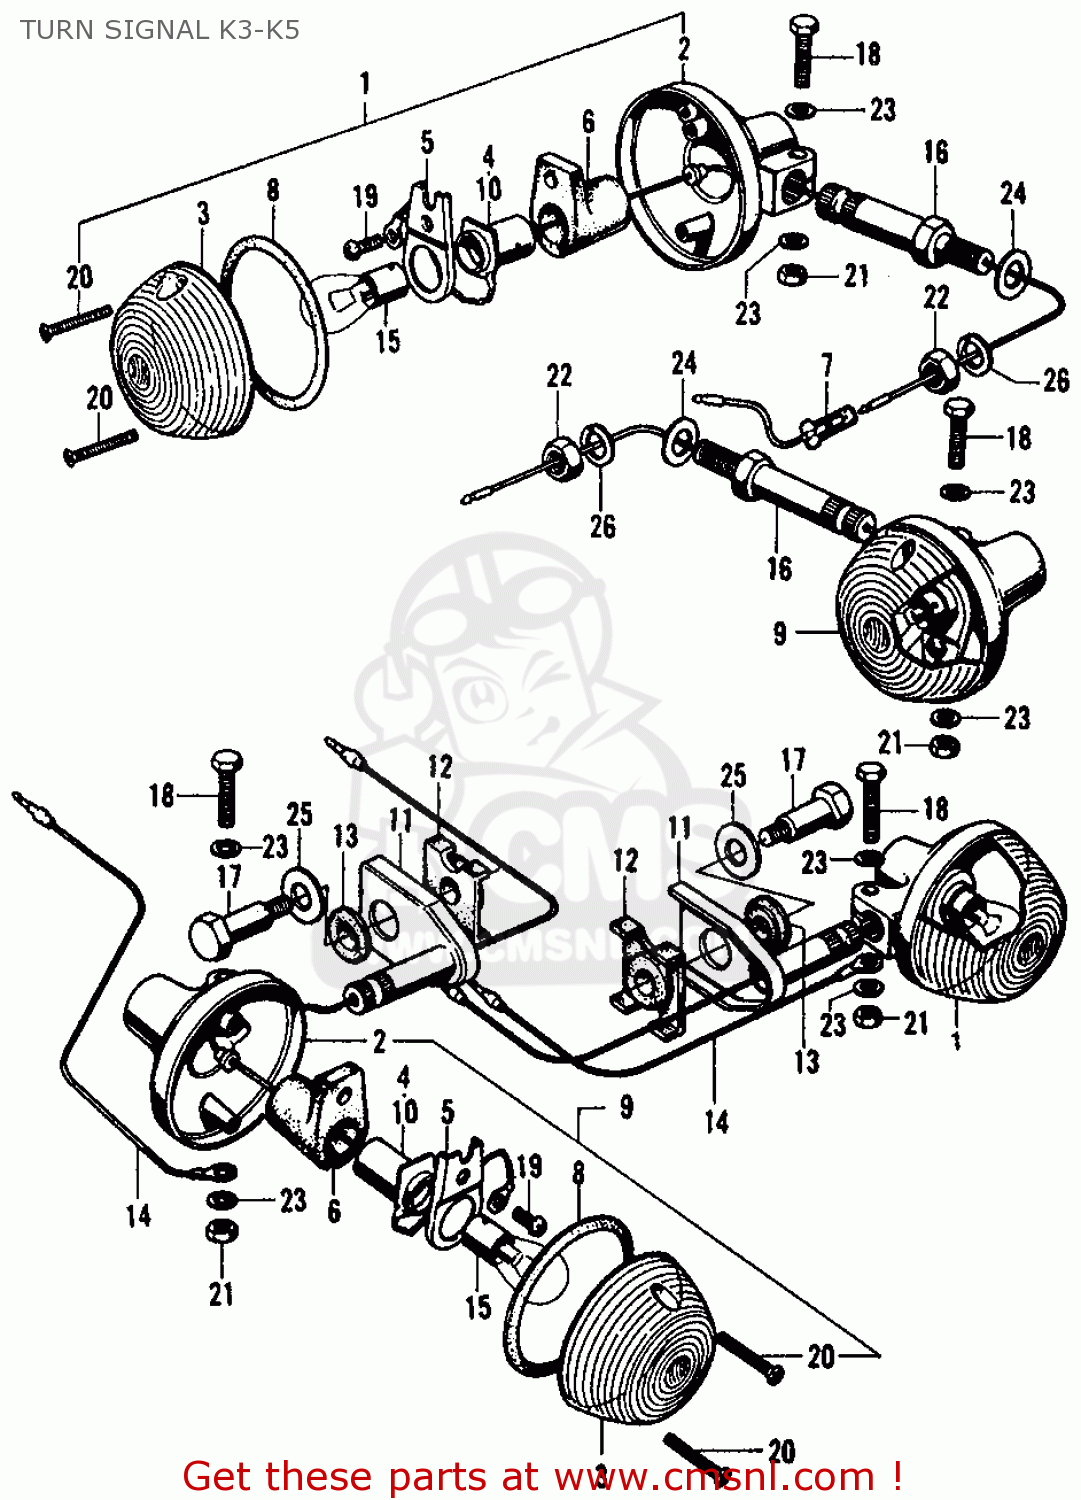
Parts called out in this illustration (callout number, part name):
1	WINKER ASSY 74IE
2	BASE,WINKER
3	LENS WINKER
4	SOCKET,R.WINKER
5	SOCKET,WINKER
6	RUBBER,WINKER
7	CORD,F.WINKER SUB
8	PACKING,LENS
9	WINKER ASSY 74IE
10	SOCKET,L.WINKER
11	STAY,REAR WINKER
12	RUBBER,MOUNT
13	RUBBER,MOUNT
14	CORD,WINKER EARTH
15	BULB, WINKER
16	BOLT, RIGHT CASE
17	BOLT,WINKER SET
18	BOLT, HEX., 6X28
19	SCREW,CROSS 5X8
20	SCREW CROSS 3X25
21	NUT HEX 6MM
22	NUT,HEX.,10M/M
23	WASHER PLAIN 6MM
24	WASHER 10MM
25	WASHER,PLAIN,12MM
26	SPG-WASHER 10MM
